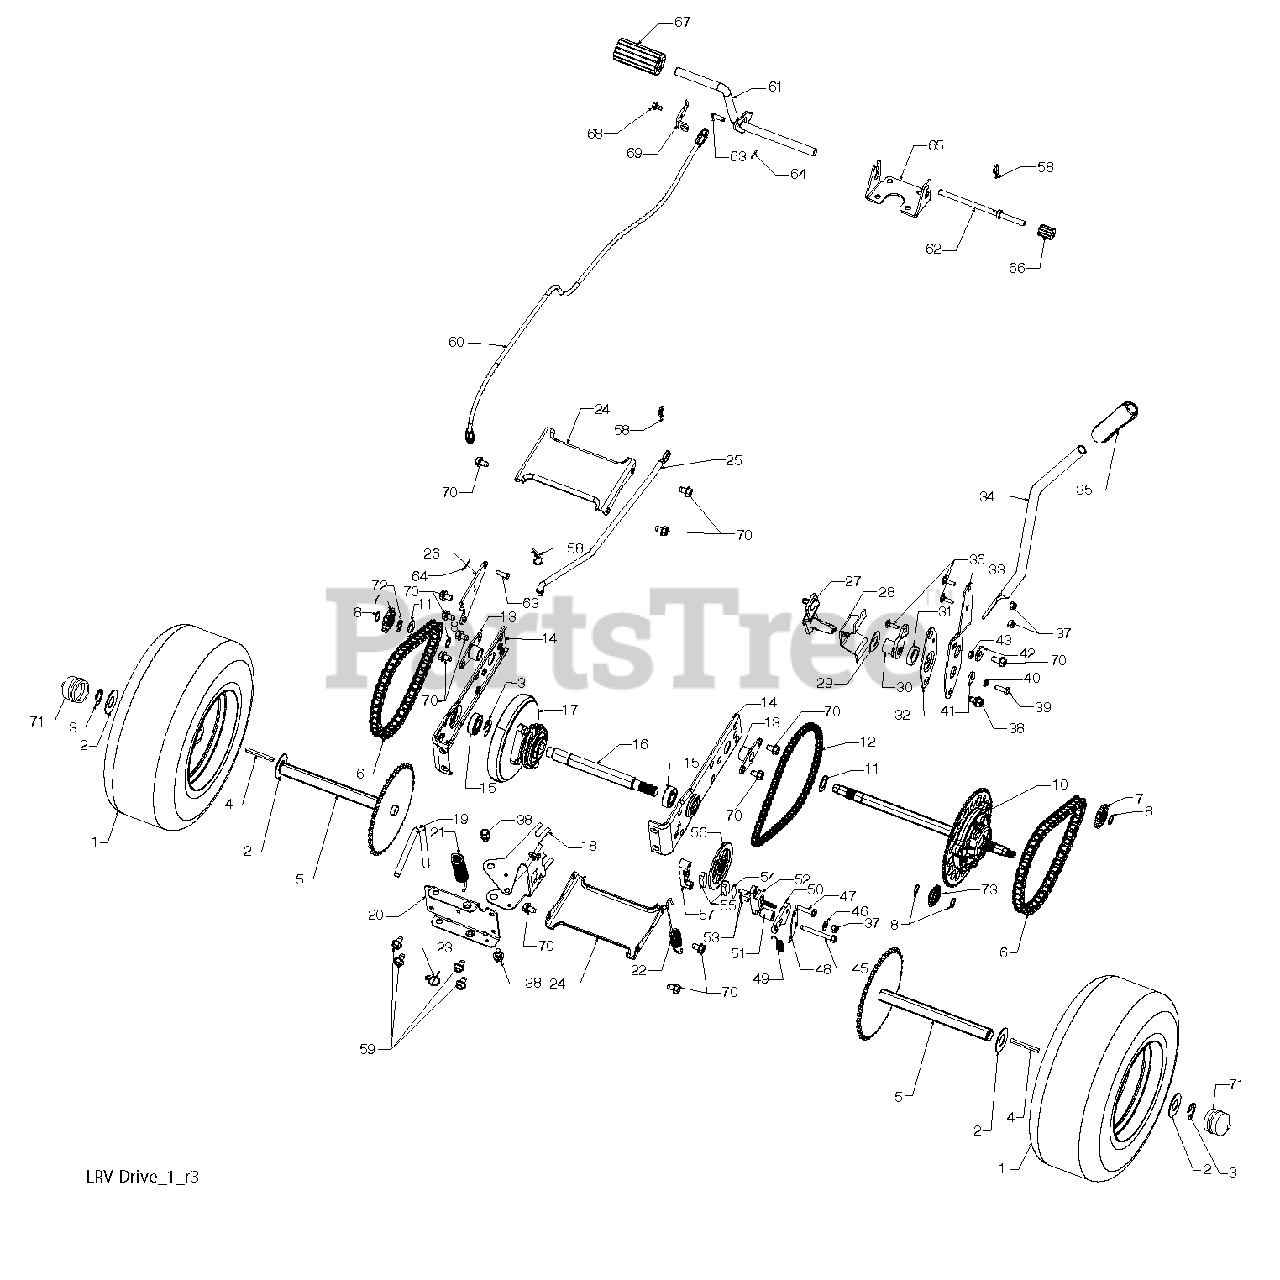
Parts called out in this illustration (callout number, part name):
1	WHEEL ASM (REAR)
2	WASHER, 16 GA.
5	WELDMENT. DRIVE AXLE
7	SPROCKET. 9 TOOTH SPLINED
10	DIFFERENTIAL ASM
11	WASHER, THRUST
12	CHAIN, PRIMARY DRIVE
14	BRACKET, CARRIER
17	WHEEL, FRICTION A5M
20	BRACE CARRIER REAR
21	SPRING, CARRIER
22	SPRING, BRAKE
23	SPRING, BYPASS
24	BRACE CARRIER BOX
25	LINK, SHIFT
27	WELDMENT SHIFT LEVER
28	SUPPORT, SHIFT LEVER
29	WASHER, NYLON
30	HUB SHIFT LEVER
31	SPACER, NYLON
32	MNTG BRKT. SHIFT ARM
33	BRACKET, SHIFTER FLEX
34	TUBE SHIFT ARM
35	GRIP, HANDLE
36	BOLT, CARRIAGE - 114-20 X 3/4
37	NUT NYLON LOCK 114-20
38	BOLT, SHOULDER
39	BOLT, 1/4-20 X 3/4
40	WASHER, LOCK
41	WASHER FLAT
42	WASHER, SERRATED
43	NUT, CROWN LOCK 114-20
45	SCREW 1/4-20 X 2 114
46	WASHER
47	SCREW, 1/4-20 X 1 1/2
48	PLATE BRAKE ANTI - ROTATE
49	SPRING, BRAKE RETURN
51	SPACER RETURN
52	CALIPER, BRAKE ASM
53	PIN, DOWEL 1/4
54	PLATE, BRAKE PAD
57	CAP, BRAKE CALIPER
58	PIN, RETAINER
59	BOLT, 5/16-16 X 112
60	CABLE, BRAKE
61	WELDMENT, PEDAL
62	ROD, PARKING BRAKE
63	PIN, .25 X .75 CLEVIS
64	PIN, 1/16 DIA. COTTER
65	BRACKET, BRAKE SUPPORT
67	COVER, BRAKE PEDAL
68	SCREW, 1/4-20 X 3/8
69	BRAKE CABLE MOUNT
70	BOLT, 5/16-18 X 3/4
72	E RING #5133-62
73	SPROCKET II TOOTH SPLINED
